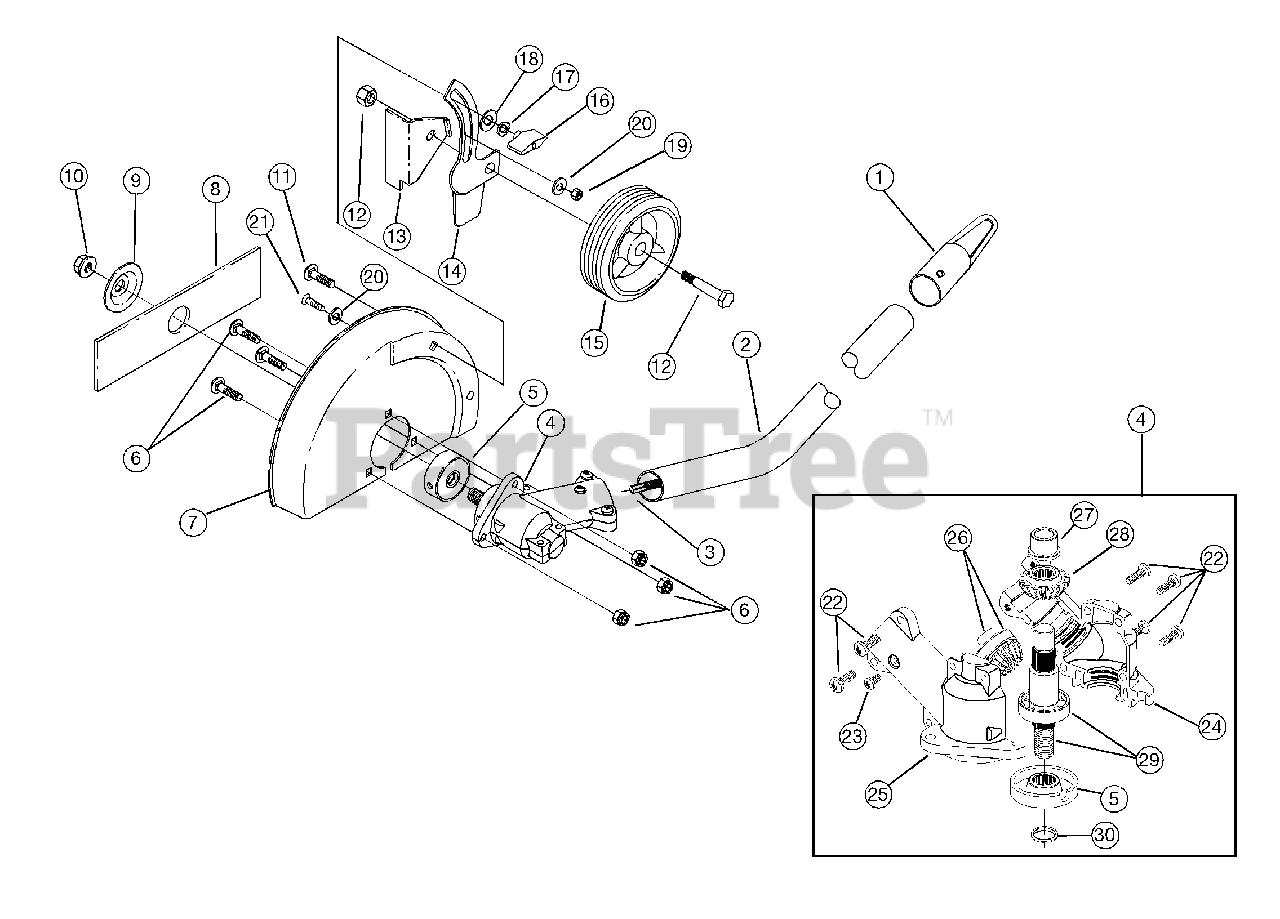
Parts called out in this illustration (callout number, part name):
1	Hanger
2	Drive Shaft Housing Assembly
3	Drive Shaft Assembly
4	Gearbox Assembly
5	Blade Driver
6	Shield Mount Screw Assembly
7	Blade Shield
8	Edger Blade
9	Retaining Washer
10	Lock Nut
11	Shoulder Bolt
12	Wheel Mounting Hardware
13	Deflector
14	Guide Bracket
16	Adjustment Knob
17	Lock Washer
19	Locknut
22	Gearbox Mounting Hardware
23	Anti-Rotation Screw
24	Left Housing
25	Right Housing
26	Pinion Gear Assembly
27	Output Shaft Bushing
28	Output Shaft Gear
29	Output Shaft Assembly
30	Palnut
